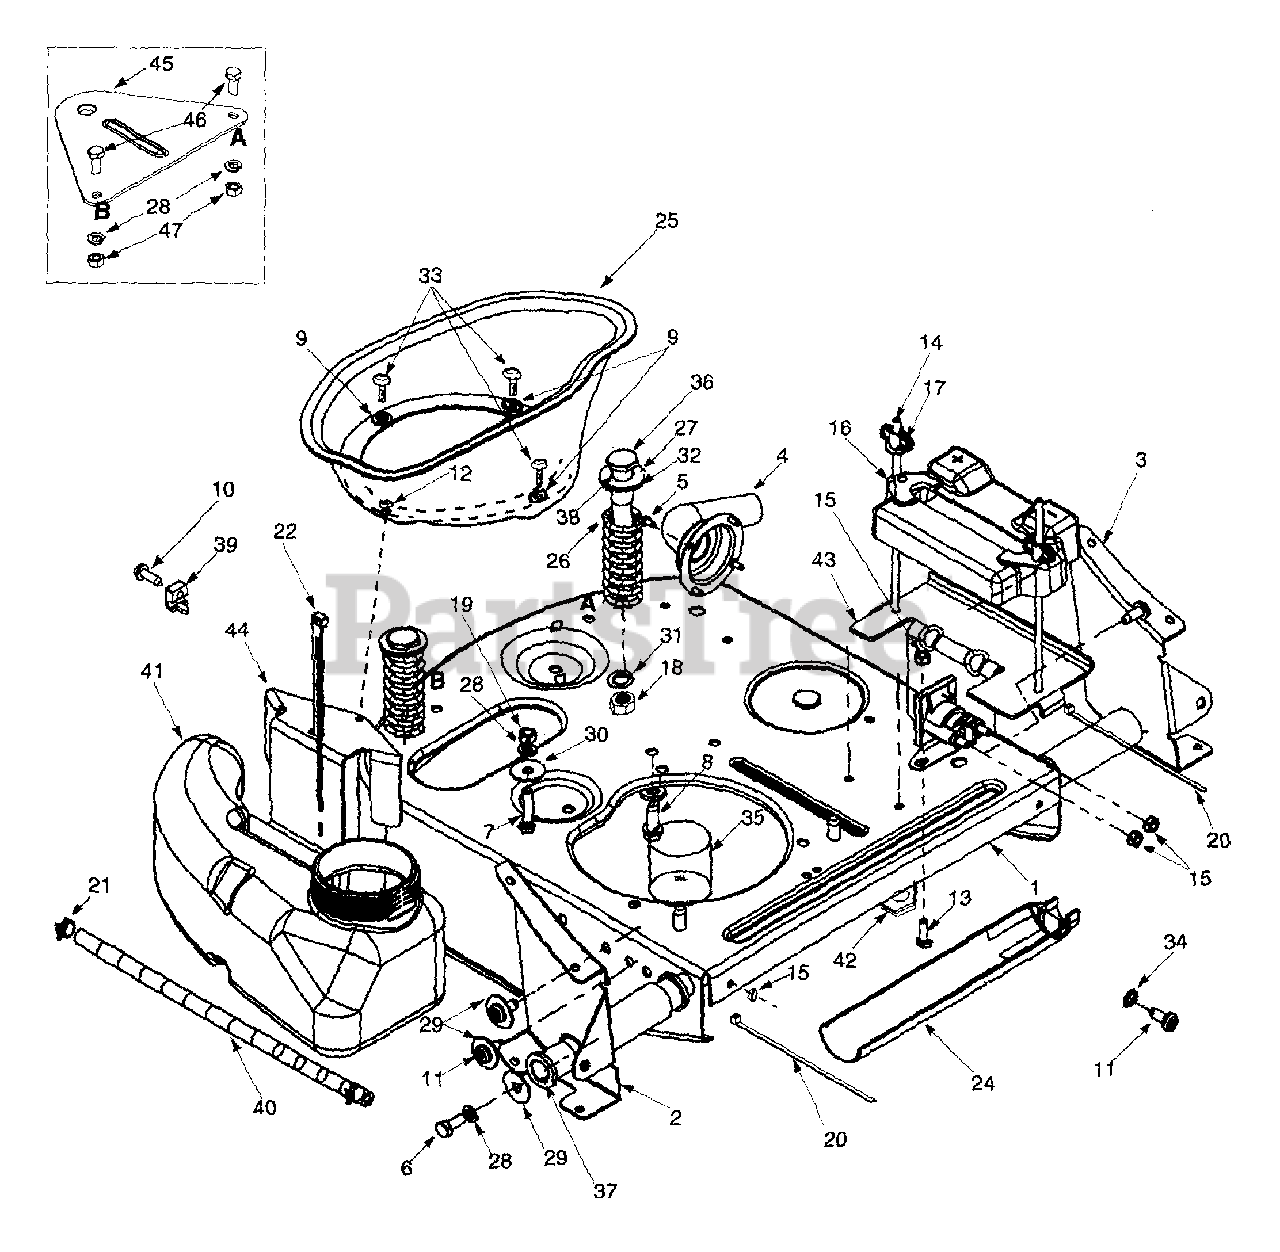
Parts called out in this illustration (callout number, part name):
5	Hex Fl. Screw #8-32 x 0.375
6	Hex Screw 5/16-24 x .75" Gr.5
7	Hex Screw 5/16-24 x 1.5" Gr 5
8	Hex Washer Head TT Screw 3/8-16 x 1.0"
9	Hex Slot Sems Screw #10-32 x 0.38
10	Hex Washer TT Screw #10-32 x 0.625"
11	TT Screw 5/16-18 x 0.75"
12	Machine Screw #10-32 x 0.5"
13	Hex Screw 1/4-20 x 0.75"
14	Battery Hold-down Rod
15	Hex Sems Nut 1/4-20
16	Lock Nut 1/4-20
17	Wing Nut with Bell Washer
18	Hex Nut
19	Hex Nut 5/16-24 Gr.5
20	Cable Tie
21	Hose Clamp
22	Cable Tie
24	Oil Drain Sleeve
25	Engine Duct
26	Compression Spring
27	Rubber Washer
28	Lock Washer
29	Flat Washer
30	5/16 Washer
31	Lock Washer
32	Flat Washer
33	Flat Washer
34	Lock Washer
35	Motor Oil
36	Shoulder Screw
37	Flange Bearing
38	Flange Bearing
39	Throttle Casing Clamp
40	Fuel Line Hose
41	Fuel Tank
46	Hex Bolt
47	Hex Nut
